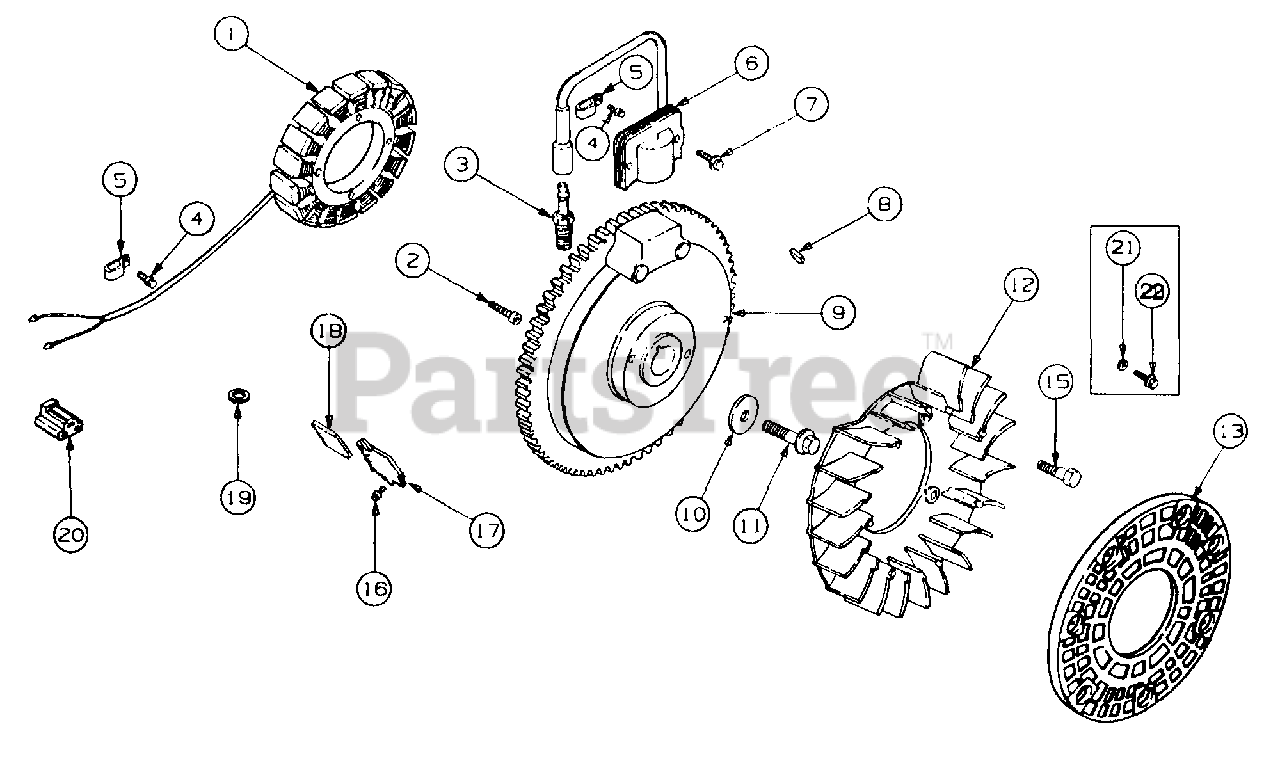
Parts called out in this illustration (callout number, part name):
1	Kit, Stator
2	Screw, Stator Mntg, M5 x .8 x 25
3	Spark Plug
4	Screw, Harness Clip, M5 x .8 x 10
5	Clip, Cable
6	Module, Ignition
7	Screw, Ign Module, M5 x .8 x 20
9	Flywheel Assembly
10	Washer, Flywheel
11	Screw, Flywheel, M10 x 1.5 x 46
12	Fan
13	Screen, Grass
15	Bolt, Shoulder M6 x 1 x 16
16	Screw, Rectifier, M6 x 1 x 16 2
17	Rectifier-Regulator
18	Connector, Three Contact
19	Washer, Lock, 1/4
20	Connector, Three Contact
21	Spacer
22	Screw
